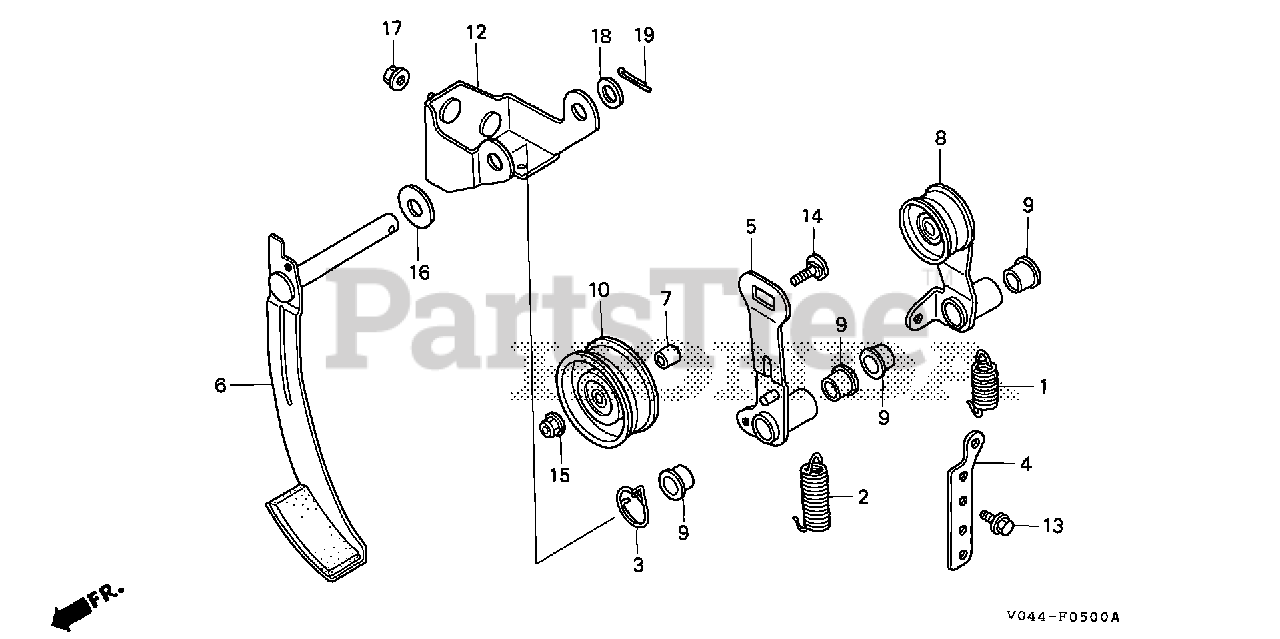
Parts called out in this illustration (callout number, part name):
1	SPRING, WHEEL TENSION RETURN
2	SPRING, AUGER TENSIONER RETURN
3	SPRING, BRAKE ARM
4	STAY, TENSIONER SPRING
5	ARM, AUGER TENSIONER
6	ARM, AUGER BRAKE
7	COLLAR, ROLLER
8	ARM, WHEEL TENSIONER
9	BUSH, TENSIONER ARM
12	BRACKET, TENSION ARM
13	BOLT, FLANGE (6X12) (CT200)
14	BOLT, ROLLER
15	NUT, SELF-LOCK (8MM) (CLINCH)
16	WASHER, BRAKE ARM
17	NUT, FLANGE (8MM)
18	WASHER, PLAIN (12MM)
19	PIN, SPLIT (3.0X18)
